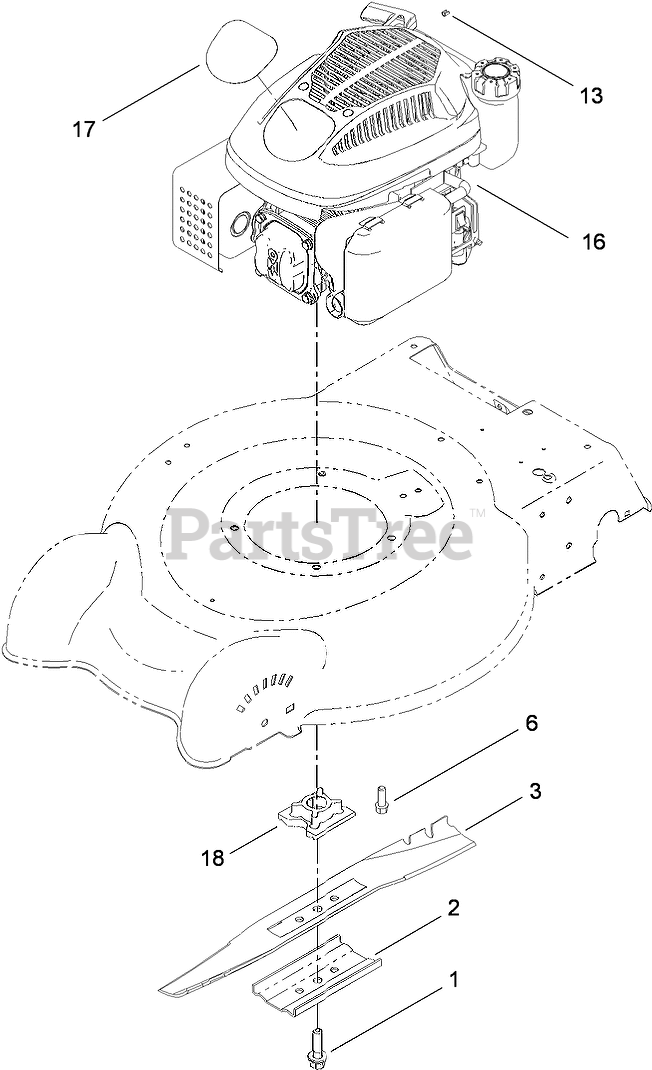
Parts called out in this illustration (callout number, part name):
1	BOLT-BLADE
2	SUPPORT-BLADE
3	BLADE-20 INCH
6	SCREW-TAPTITE
13	STOP-ROPE
16	ENGINE-LC1P65FA
17	DECAL-SHROUD
18	RETAINER-BLADE
